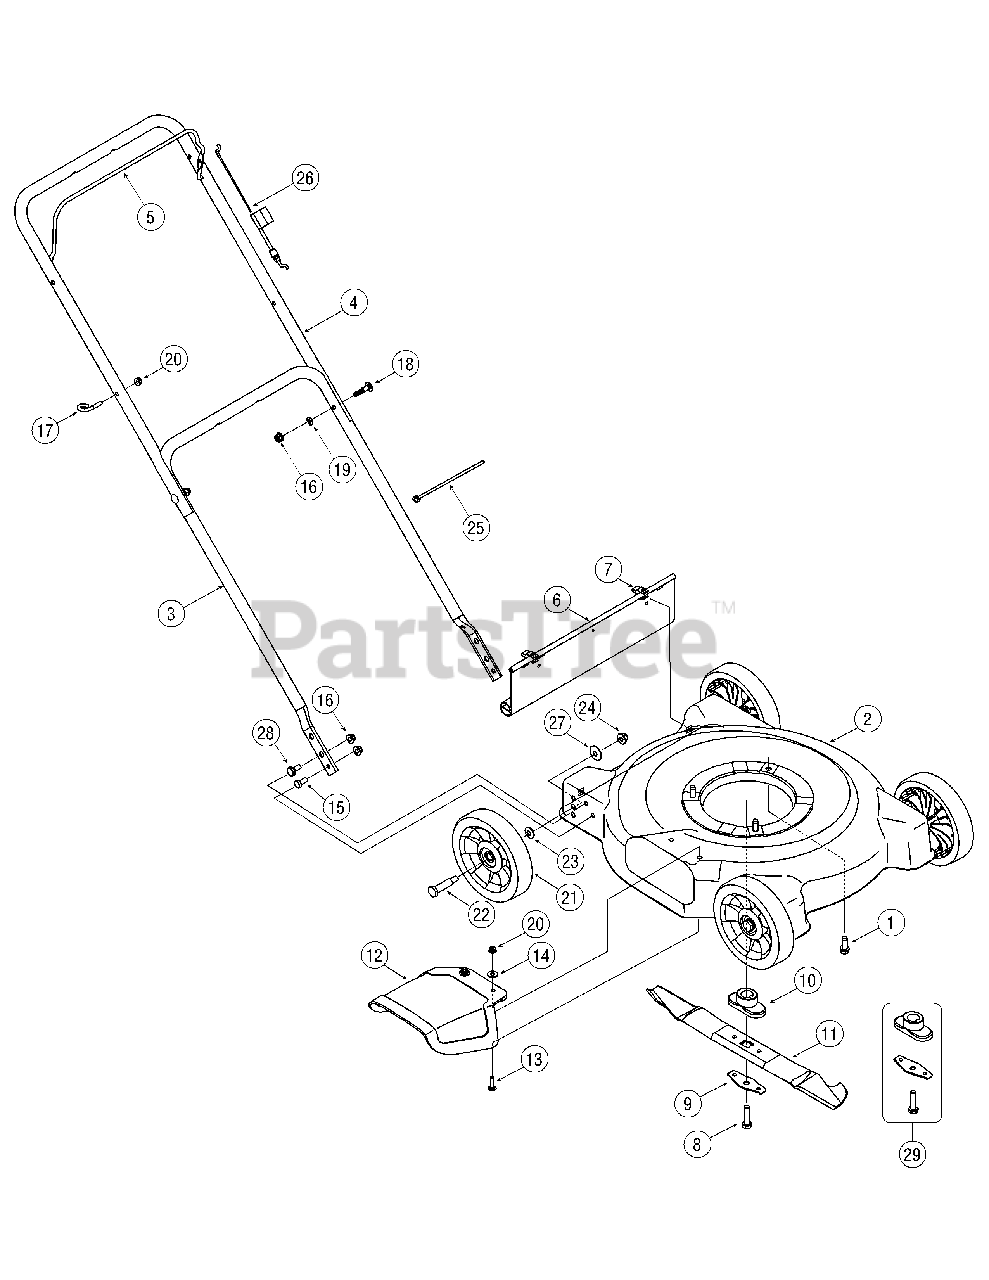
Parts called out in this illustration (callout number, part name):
1	Hex Ind. Washer Screw 3/8-16 x 1.0
6	Rear Flap
7	Hinge Clip
8	Screw 3/8-24 x 1.5" Group 8
9	Blade Bell Support
10	Blade Adapter
11	Cutting Blade
12	Discharge Chute
13	Carriage Screw 1/4-20 x 1.0"
14	Flat Washer
15	Hex Screw 5/16-18 x .75"
16	Flange Lock Nut 5/16-18
17	Eye Bolt
18	Carriage Bolt 5/16-18 x 1.5"
19	Lock Washer
20	Flange Lock Nut 1/4-20
21	Wheel
22	Shoulder Screw .498 x 1.635
23	Bell Washer
24	Flange Lock Nut 3/8-16
25	Cable Tie
26	Control Cable (Model 021)
26	Control Cable (Models 020 & 022)
27	Bell Washer
28	Shoulder Screw, 5/16-18 x.428"
29	Blade Adapter Kit (Incl. Ref. 8-10)
